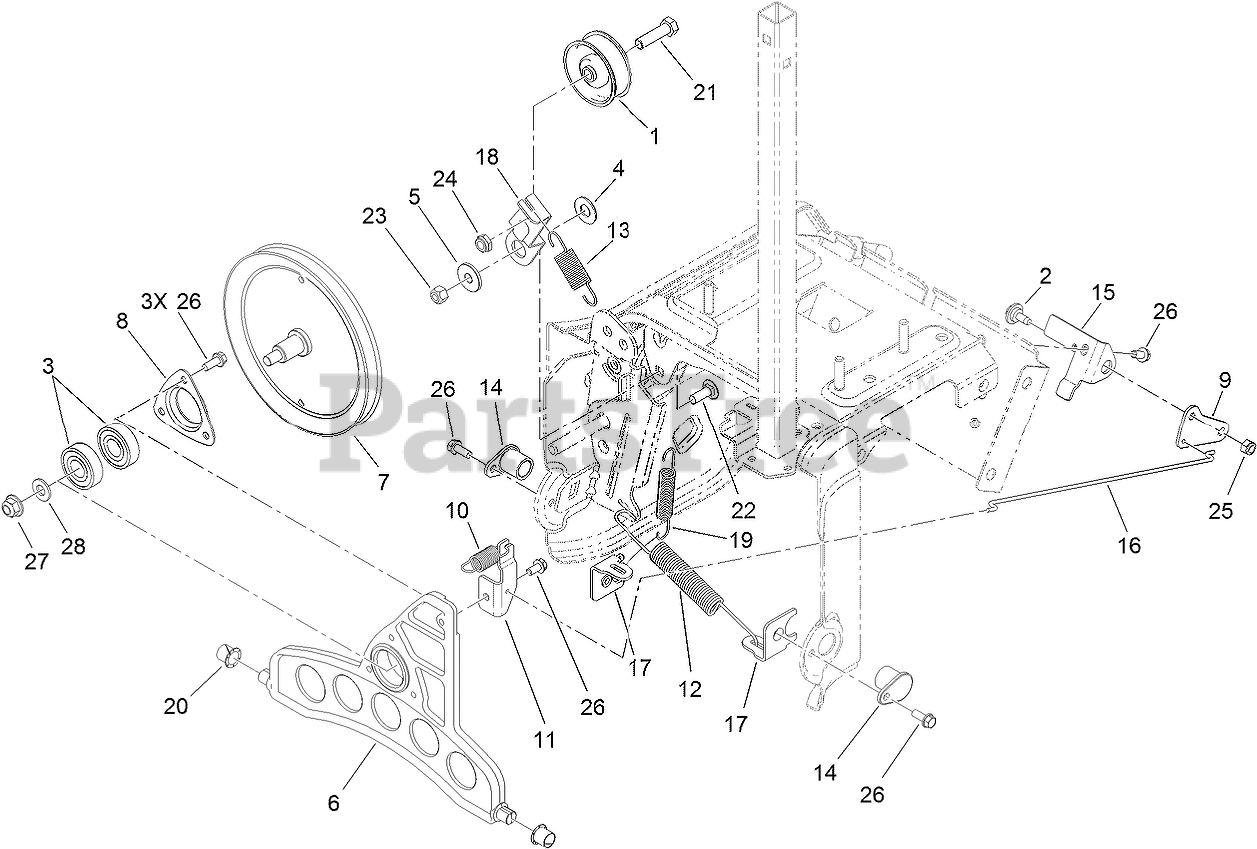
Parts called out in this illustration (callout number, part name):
1	PULLEY-IDLER
2	SCREW-SHOULDER
3	BEARING-BALL
4	WASHER
5	BUSHING-IDLER
6	PLATE-WHEEL, FRICTION
7	PULLEY-TRACTION
8	RETAINER-BEARING
9	BELLCRANK-DRIVE
10	SPRING-EXTENSION
11	BRACKET-PLATE, TRACTION
12	SPRING-EXTENSION
13	SPRING-EXTENSION
14	BUSHING-PLATE, TRACTION
15	BRACKET-BELLCRANK
16	LINK-DRIVE
17	BRACKET-ANCHOR, SPRING
18	ARM-IDLER, TRACTION
19	SPRING-EXTENSION
20	BUSHING-NYLINER
21	SCREW-HH
22	BOLT-CARR
23	NUT-LOCK, NI
24	NUT-LOCK, NI
25	NUT-LOCK, NI
26	SCREW-HWH
27	NUT-HF, NI
28	WASHER-FLAT
